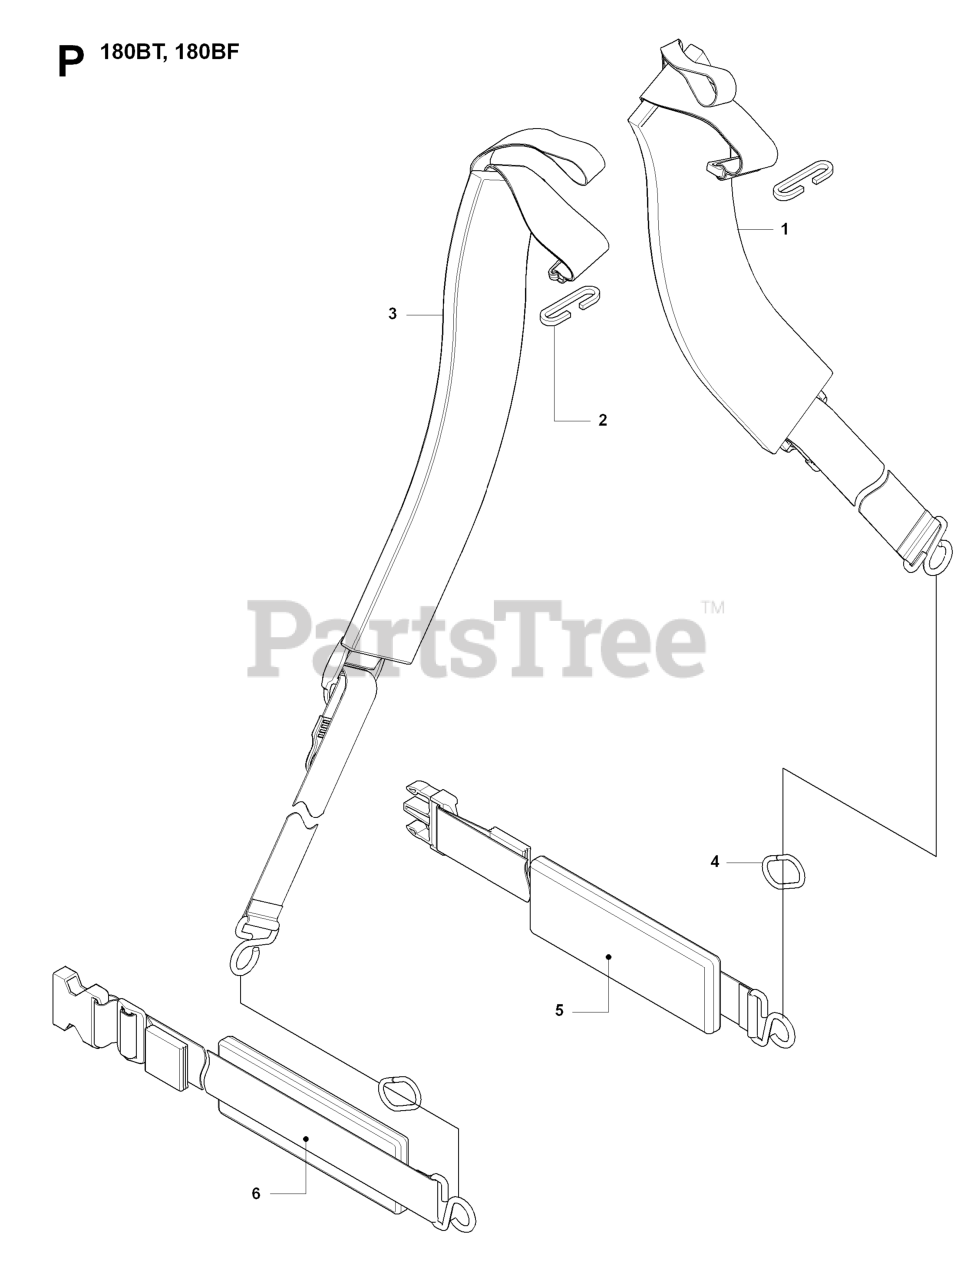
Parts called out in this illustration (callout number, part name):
1	BAND ASSY (R)
3	BAND ASSY (L)
4	RING
5	BAND B(R)
6	BAND B(L)
